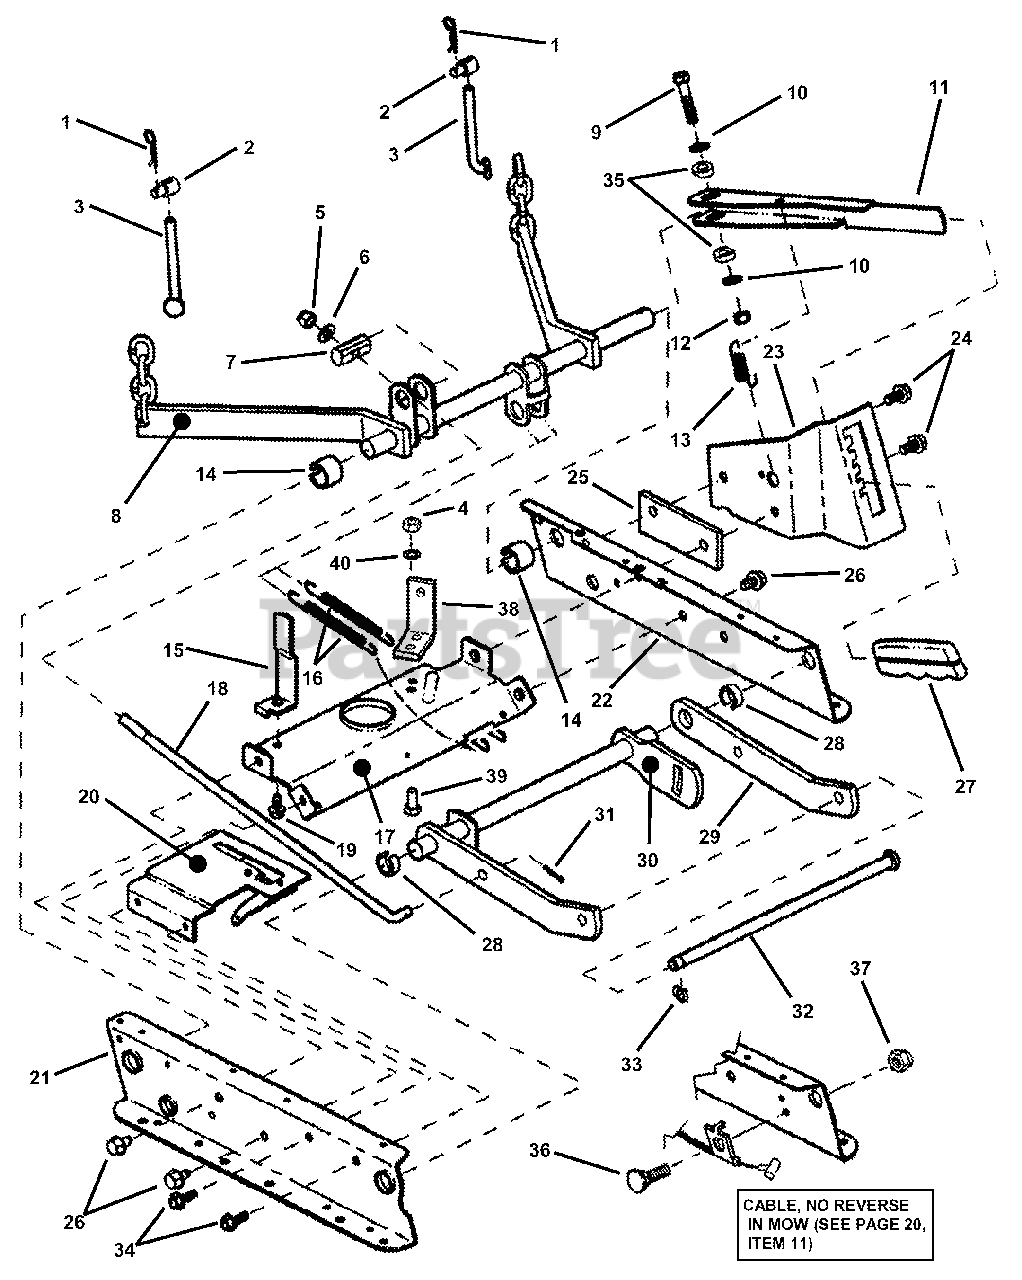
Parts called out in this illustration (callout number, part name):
1	HAIRPIN, 3/32" X 1-1/2"
2	SWIVEL
3	HOOK, Chain
4	NUT, 5/16-24 Hex
5	NUT, 3/8-24 Hex Nyloc
6	WASHER, 3/8" Flat
7	PIVOT, Leveling
8	ARM, Rear Lift (weldment)
9	SCREW, 3/8-24 X 1-3/4" Hex Head Cap Grade 5
10	WASHER, 13/32" Flat
11	LEVER, Height of Cut
12	NUT, 3/8-24 Hex Center Lock
13	SPRING, Lever
14	RING, Blue
15	GUIDE, Belt
16	SPRING, Assist
17	BRACE, Top
18	ROD, Leveling
19	SCREW, 5/16-18 x 5/8" Self-Tap
20	ASSEMBLY, Clutch Plate
21	RAIL, Deck Lift, Right Hand
22	RAIL, Deck Lift, Left Hand
23	DETENT, Height Adjust
24	SCREW, 3/8-16 x 1" Hex Washer Self-Tap
25	DETENT, Spacer
26	SCREW, 3/8-16 x 5/8" Hex Washer Self-Tap
27	GRIP, Height Adjustment Lever
28	RING, Red
29	ARM, Front Lift
30	ARM, Front Lift (Weldment)
31	PIN, 1/8 x 3/4" Cotter
32	ROD, Support
33	SNAP RING, 7/16"
34	SCREW, 5/16-18 X 1/2" Hex Washer Self-Tap
35	SPACER, Deck Lift
36	BOLT, #10-24 x 1" Flat Head Square Neck
37	NUT, #10-24 Hex Nyloc
38	ANCHOR
39	SCREW, 5/16-24 x 3/4" Hex Head Cap, Grade 5
40	WASHER, 5/16" Internal Tooth Lock
